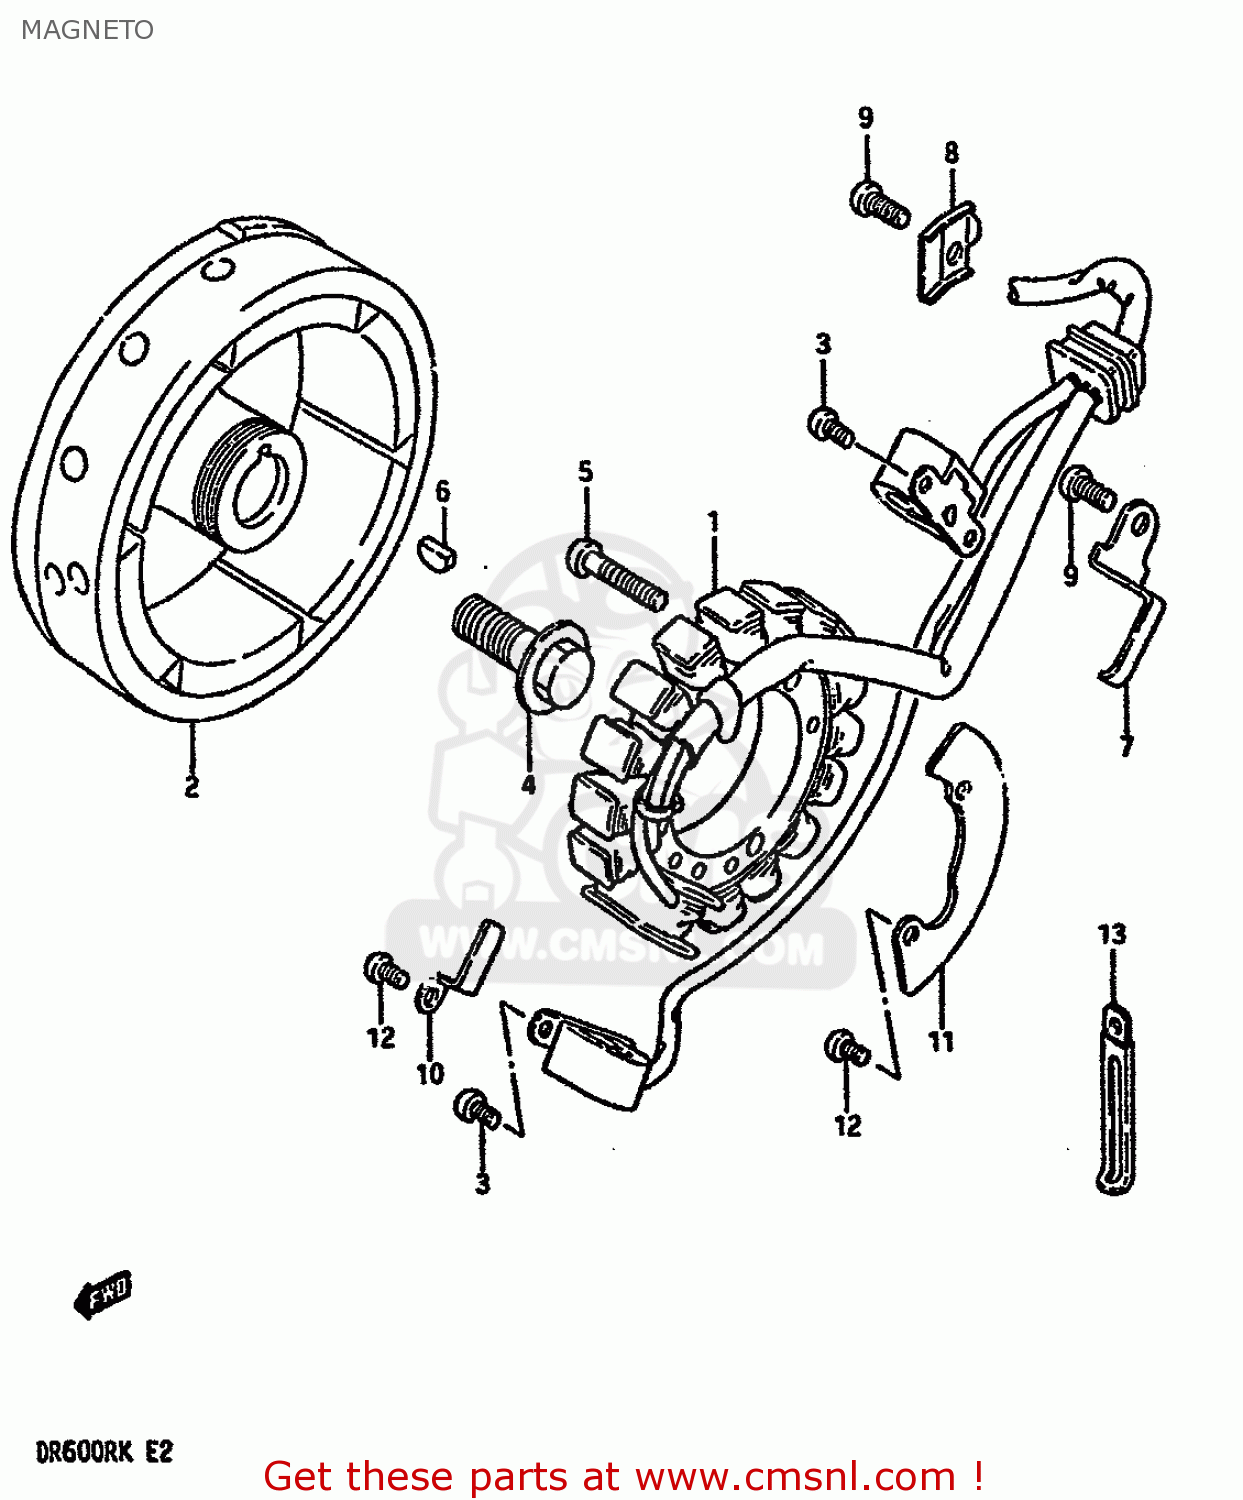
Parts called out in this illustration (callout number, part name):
1	STATOR ASSY
2	ROTOR,FLYWHEEL
3	SCREW
4	BOLT(14X43)
5	SCREW 6X30
6	KEY 4MM
7	CLAMP,MAGNETO LEAD WIRE
8	CLAMP,MAGNETO LEAD WIRE
9	SCREW
10	CLAMP
11	CLAMP
12	SCREW
13	CLAMP
